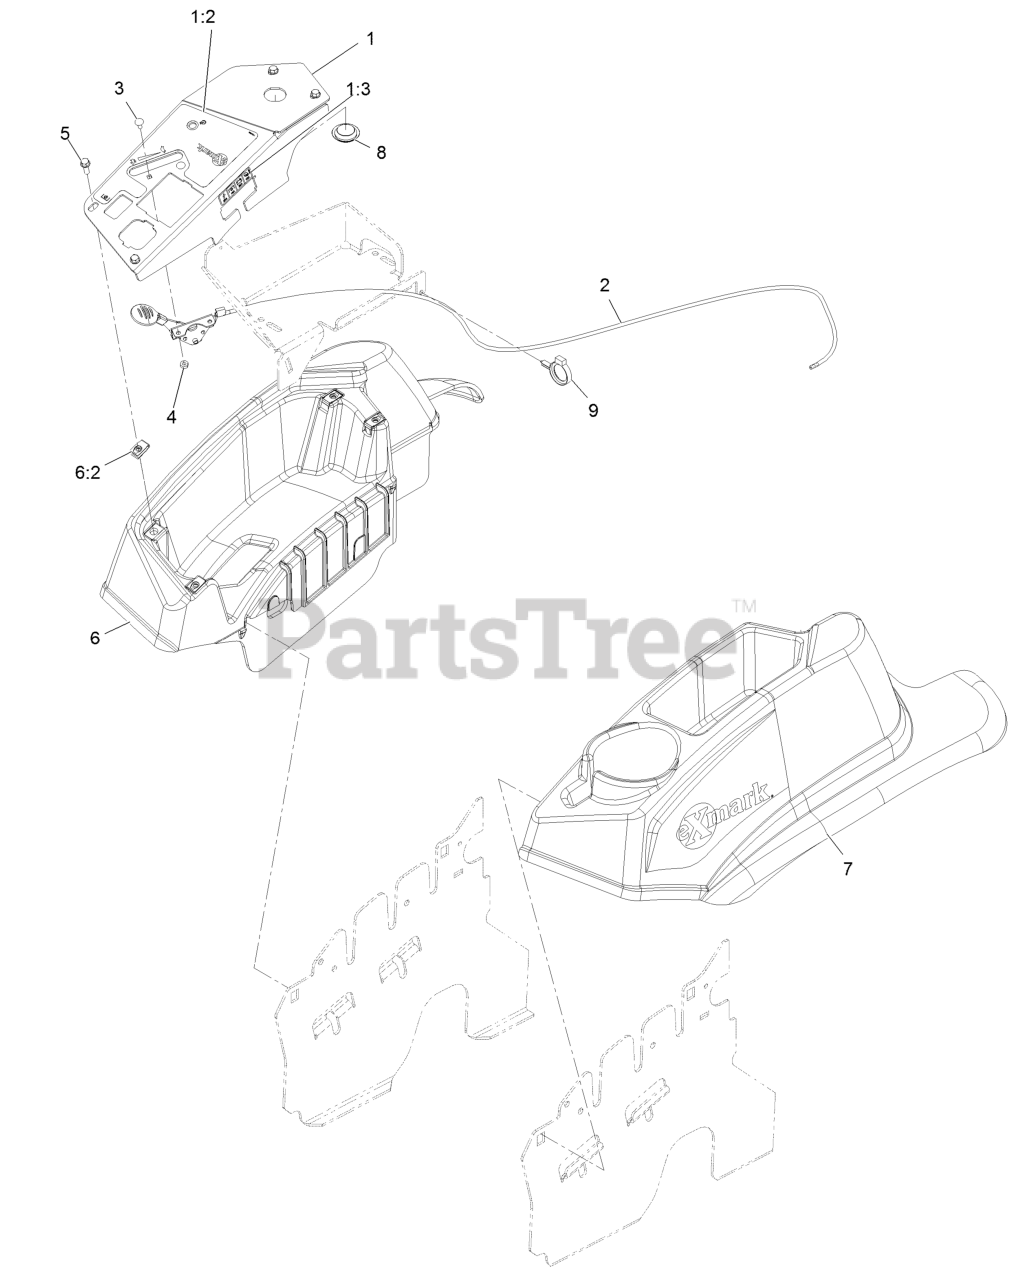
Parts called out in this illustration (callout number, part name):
1	ASM,CONTROL PANEL W/DECAL
1:2	DECAL-CONTROL PANEL EFI
1:3	DECAL-FUSES
2	ASM,THROTTLE CABLE
3	BOLT-CARR
4	NUT-LOCK, NI
5	SCREW-HWH
6	CONSOLE,RH AS ASM
6:2	Nut-Retainer-Panel 1/4-20
7	CONSOLE, LH AS
8	PLUG-PLASTIC
9	CLAMP-HOSE
